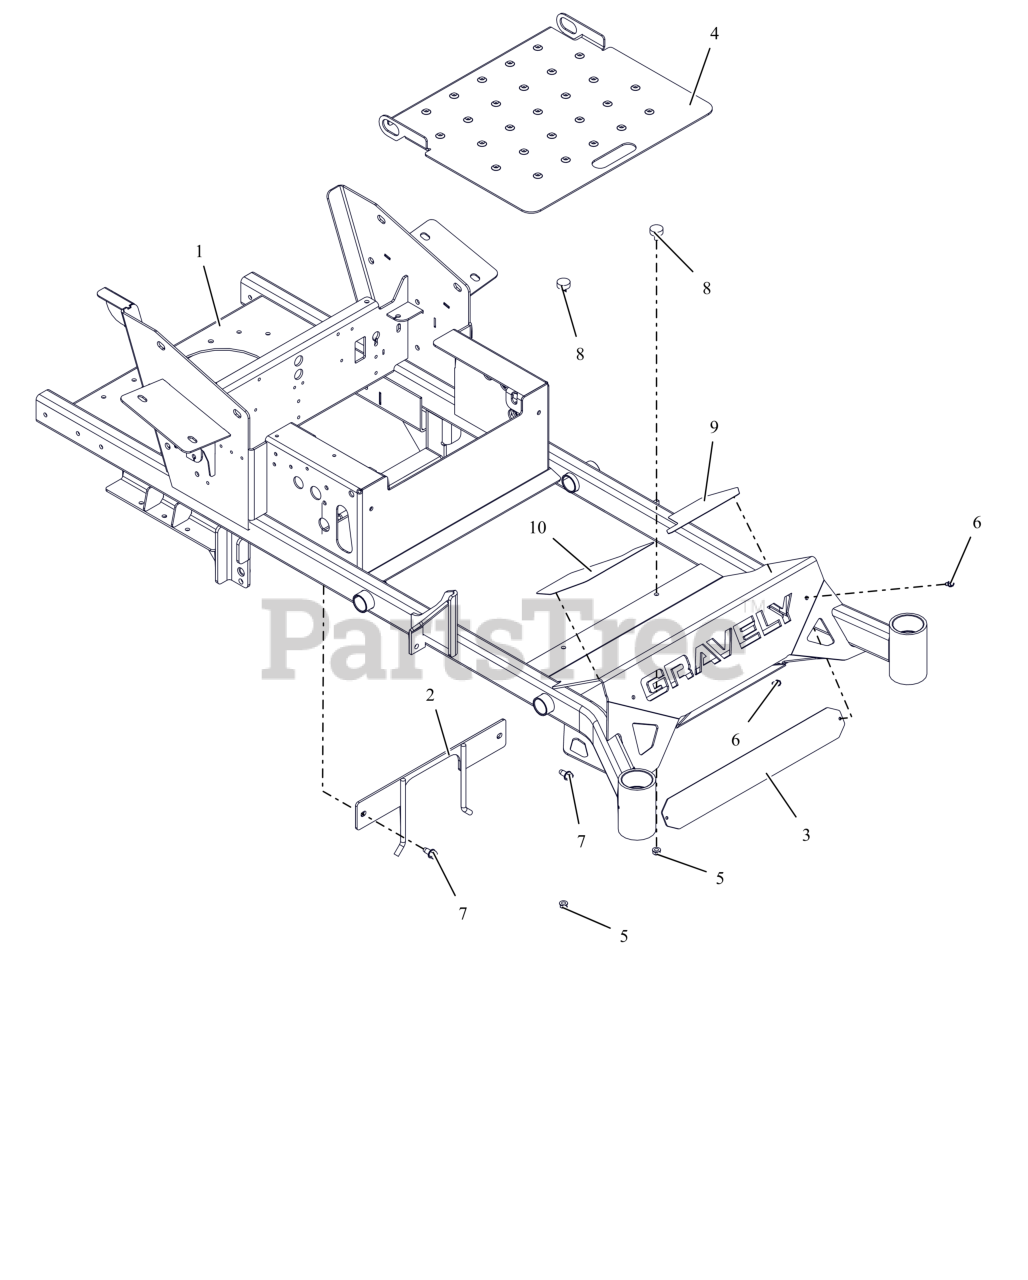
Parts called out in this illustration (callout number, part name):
1	PT/100 48-52 FRM W/SAFETY DECL
2	PTO BELT FINGER WLDMT - BLK
3	BUMPER LOGO BACKING PLATE -BLK
4	PT/100 FOOT PLT W/SAFETY DECAL
5	NUT,SPNLK-FLG .31-18 G5 ZCC
6	SCR-TAP .25-20X.50 HWH ZCC
7	SCR,TAP .375-16X.75 HWH TR ZCC
8	BUMPER, RUBBER
9	GRIP, LH FOOT PLATE
10	GRIP, RH FOOT PLATE
